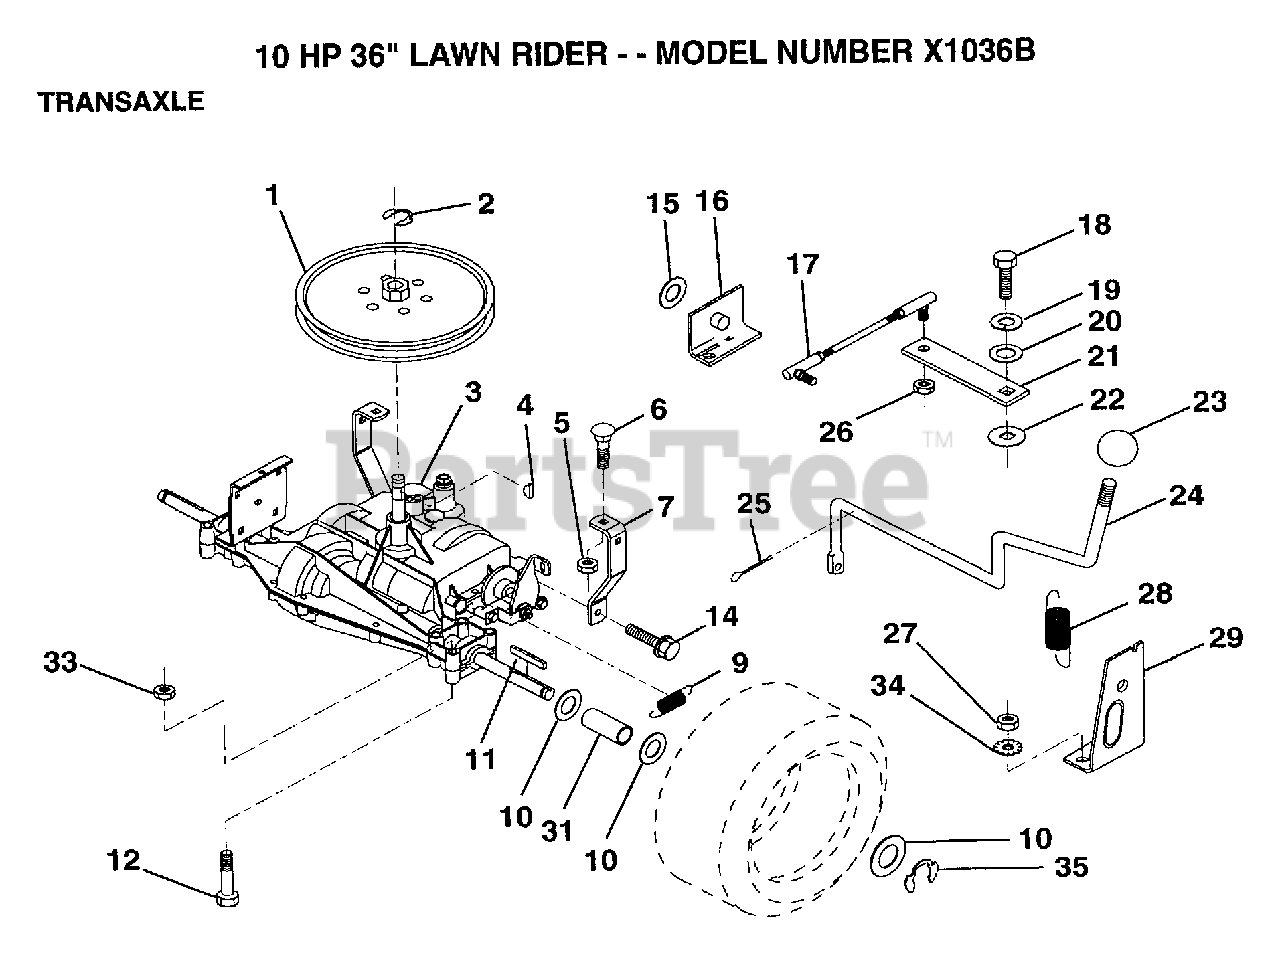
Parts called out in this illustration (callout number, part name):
6	BOLT
7	"STRAP,TORQUE"
10	WASHER
11	SQUARE KEY
12	BOLT
14	SCREW
16	"SUPT,HDLE SHT LH"
17	"LINK,SHIFT"
19	LOCKWASHER
20	WASHER LT
21	ARM SHIFT
22	WASH-SHFT PLT LT
23	KNOB T (1/2-HOLE)
24	"ROD,SHIFT"
25	PIN COTTER 1/8
26	NUT.LOCK.5/16-24
28	"SPRING,EXT"
29	"SUPT,HDLE RH"
31	SPACER
34	LOCKWASHER.5/16.E
35	E-RING LT
